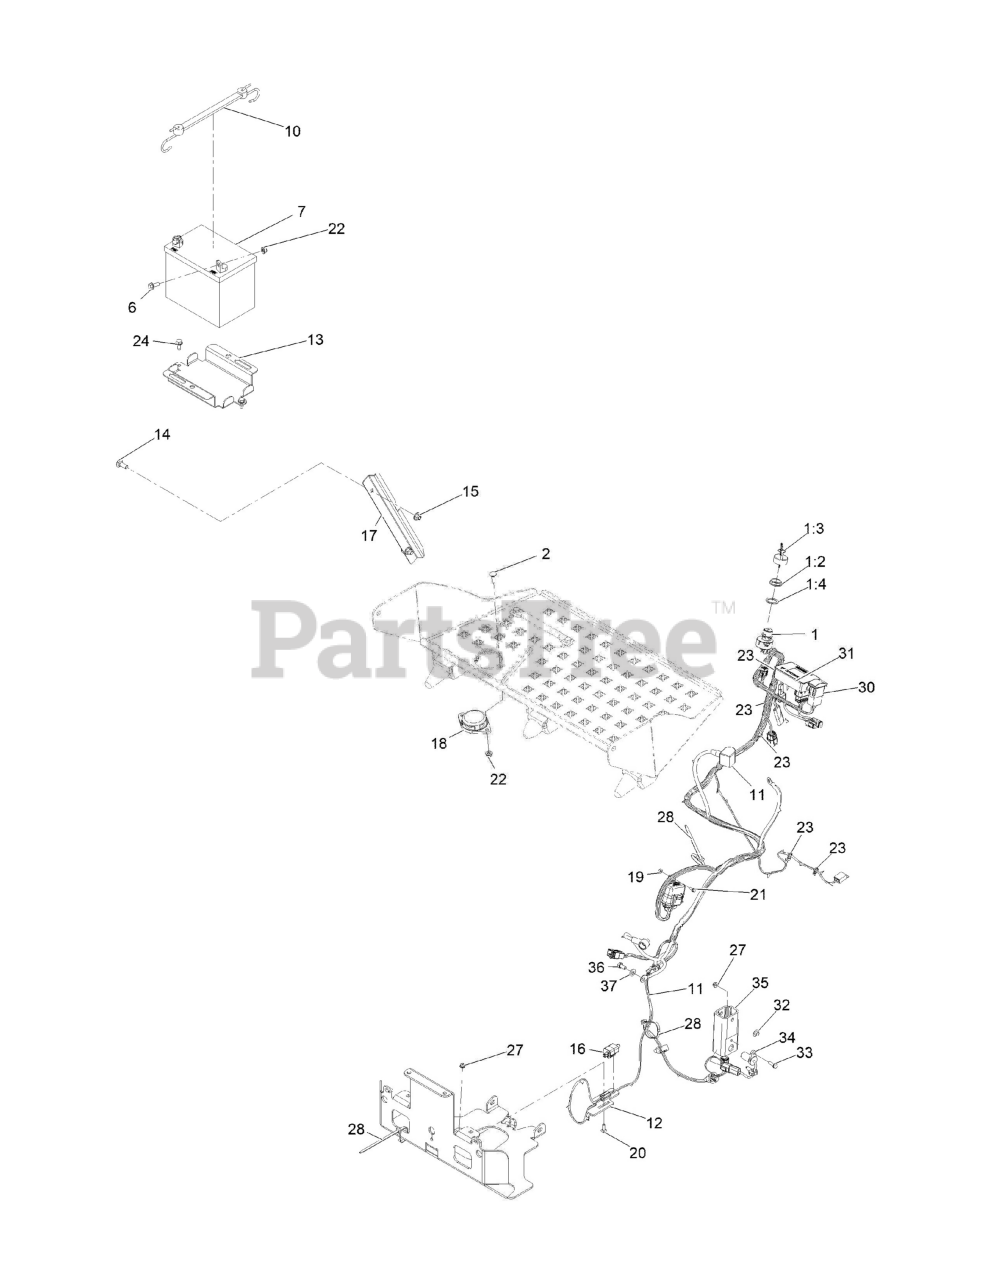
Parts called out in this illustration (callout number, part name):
1	IGNITION SWITCH ASM
1:2	NUT-MOUNTING
1:3	IGNITION KEY SET
1:4	WASHER-BACKUP
2	BOLT-CARR
6	SCREW-HHF
7	Battery
10	HOLDDOWN-BATTERY
11	Harness-Wire
12	MOUNT-SWITCH
13	BRACKET-BATTERY
14	BOLT-CARR
15	NUT-HF, NI
17	GUARD-HARNESS
18	SWITCH-SEAT
19	NUT-LOCK, NI
20	BOLT-CARR
21	SCREW-HWH
22	NUT-HF, NI
23	TIE-CABLE
24	Screw-HWH 5/16-18 X 3/4 Tf
28	TIE-CABLE
31	Hour Meter ASM
32	Nut-Push
33	SCREW-HWH
34	Sensor, Quadrature
35	Housing-Depth Control 30
36	SCREW-HH
37	WASHER-PLAIN
